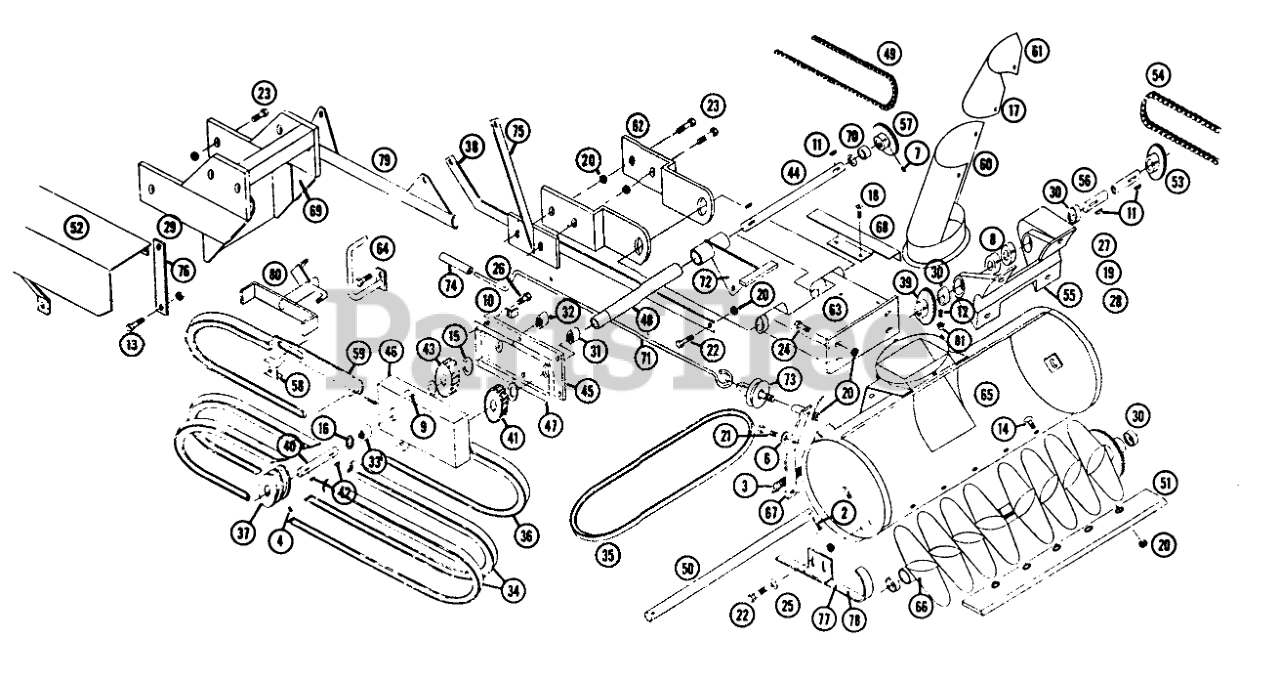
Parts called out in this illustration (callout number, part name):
1	Cotter Key
2	Cotter Pin
3	Spring
4	Snap Ring
5	Lockwasher
6	Flat Washer
7	Set Screw 1/4-20 x 1
8	Collar
9	Pipe Plug
10	Lockwasher 1/4
11	Key-#9
12	Hex Head Cap Screw
13	5/16-24 x 1/2 H.H.C.S.
14	3/8-16 x 3/4 Flat Hd. Mach. Screw
15	WASHER
16	Seal
17	1/4-20 Wing Nut
18	H.H.C.S. 1/4-20 x 1/2
19	1/4-20 Lock Nut
20	Nut
21	Bolts 3/8-16 x 3/4
22	Bolt 3/8-16 x 1
23	Collar w/Setscrew
24	Key 1/4 x 1/4 x 1
25	3/8 Washer
26	1/4-20 x 3/4 H.H.C.S.
27	1/4 Washer
28	1/4-20 x 1/2 Round Hd. Mach. Screw
29	Bolt 1/4-20 x 1 CP
30	Ball
31	BEARING-NEEDLE
32	BEARING-NEEDLE
33	NEEDLE BEARING
34	V BELT
35	V" Belt Chute 45
36	"V" Belt (A) 74" Lg. for ST-302
37	Sheave
38	Lift Arm
39	Sprocket
40	Drive Shaft
41	Jack Shaft Gear
42	Woodruff Key #9
43	Drive Gear
44	Lower Drive Shaft
45	Cover
46	Gear Box
47	Gasket
48	Pivot Tube
49	Chain
50	Reel Shaft
51	Wear Plate
52	Belt Guard
53	Sprocket
54	Chain
55	Mounting Bracket
56	Jack Shaft
57	Sprocket
58	Brace
59	Clutch Rod
60	Chute
61	Chute Deflector
62	Front Mounting Bracket
63	Mounting Channel
64	Belt Idler Bracket
65	Shroud
66	Reel Ass-y.
67	Pivot Bar
68	Shield
69	Mounting Bracket (Special)
70	Spacer
71	Snap Ring
72	Lift Ass-y.
73	Eye Bolt Sheave
74	Handle
75	Pivot Crank Support
76	Bracket used on ST-302
77	Skid R.H.
78	Skid L.H.
79	Lift Rod
80	Clutch Pedal for ST-302
81	Bushing
82	SPACER
